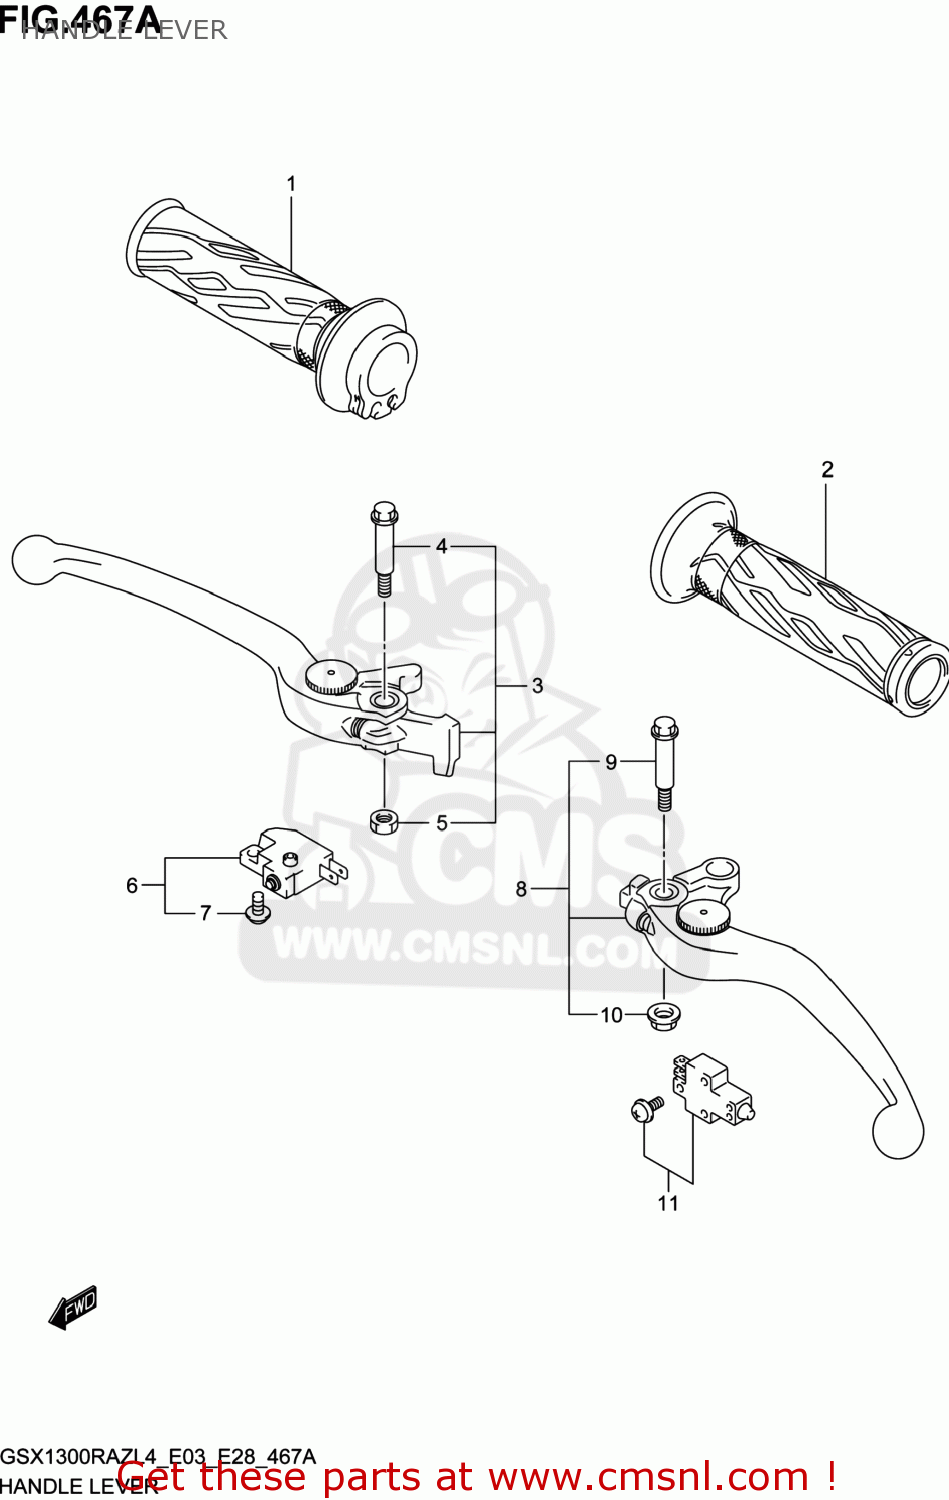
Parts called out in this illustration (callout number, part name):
1	GRIP,THROTTLE
2	GRIP,L
3	LEVER ASSY,FR BRAKE
4	BOLT,LEVER PIVOT
5	NUT
6	SWITCH ASSY,FR BRAKE
7	SCREW
8	LEVER ASSY,CLUTCH
9	BOLT,LEVER PIVOT
10	NUT
11	SWITCH ASSY,CLUTCH
